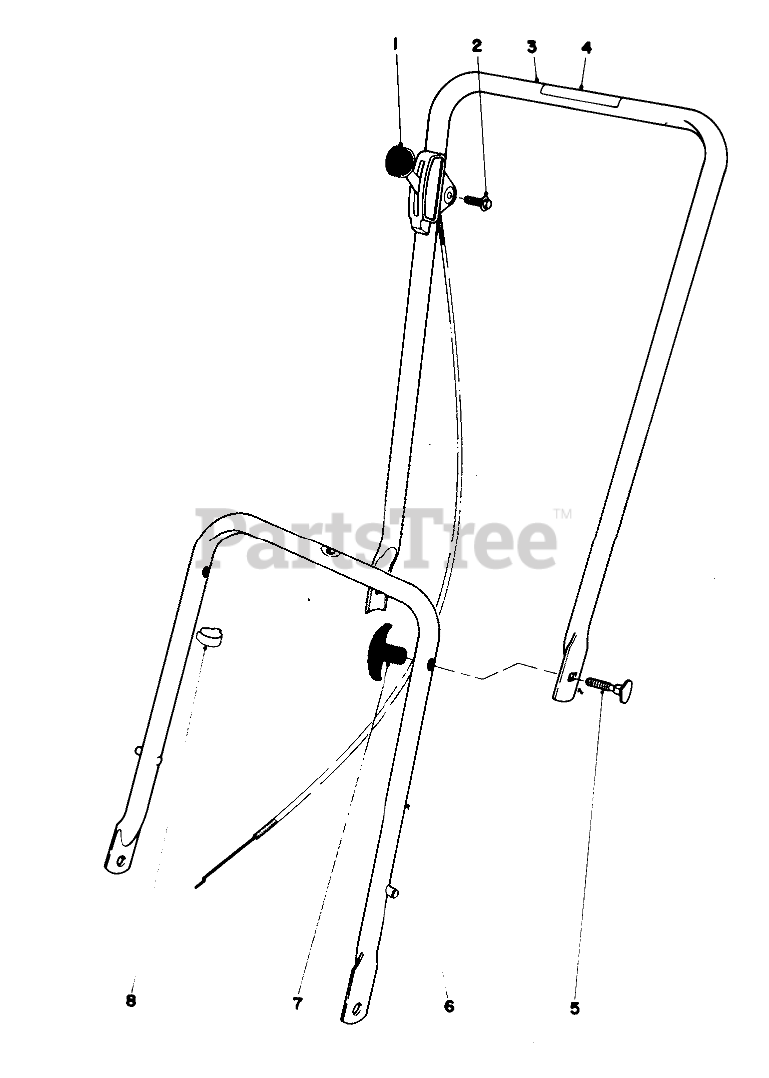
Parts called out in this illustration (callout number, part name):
1	Throttle Control
3	UPPER HANDLE
4	Decal
5	HANDLE SCREW
6	Lower Handle
